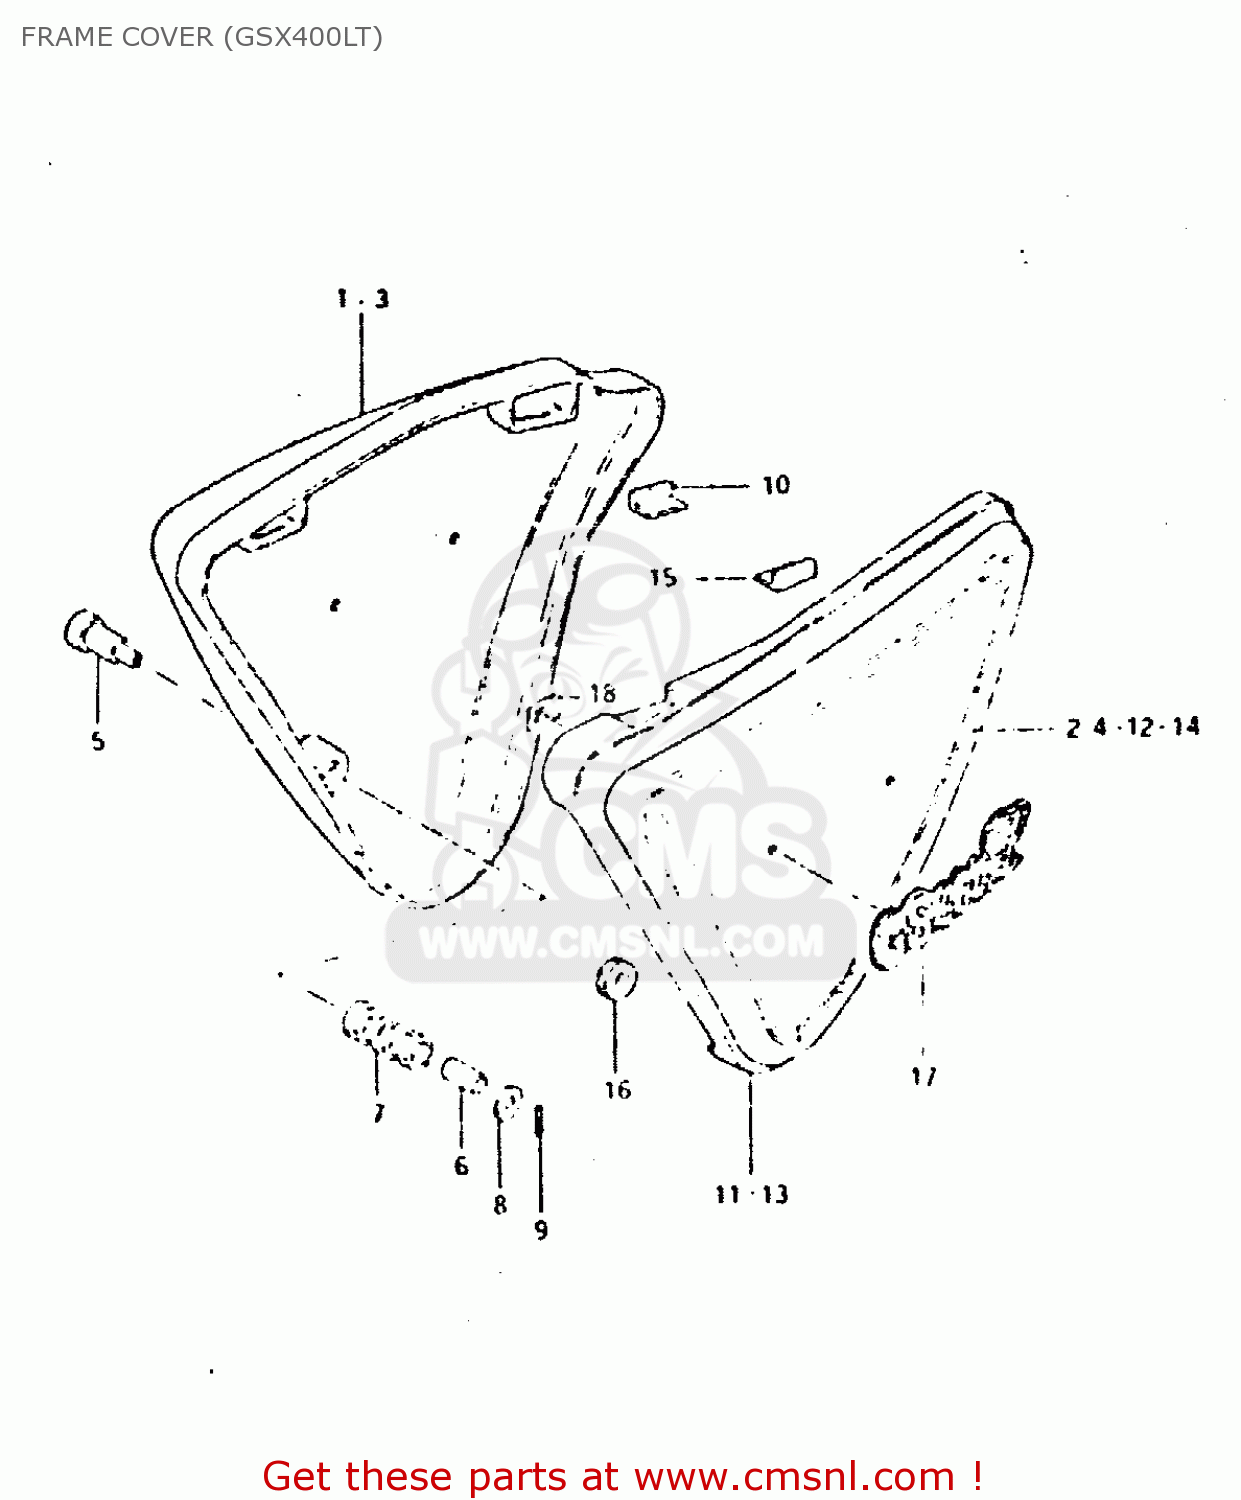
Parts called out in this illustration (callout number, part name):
1	COVER,FRAME,RIGHT
2	TAPE SET,FRAME COVER
3	COVER,FRAME,RIGHT
4	TAPE SET,FRAME COVER,RIGHT
5	KNOB,FRAME COVER,R
6	SPACER(14.9X17.3X13.5)
7	SPRING
8	WASHER (6.5X24X1.6)
9	PIN,SPRING(2.5X18)
10	CUSHION,FRAME COVER
11	COVER,FRAME,LEFT
12	TAPE SET,FRAME COVER
13	COVER,FRAME,LEFT
14	TAPE SET,FRAME COVER,LEFT
15	CUSHION,FRAME COVER
16	CUSHION
17	EMBLEM
18	NUT
